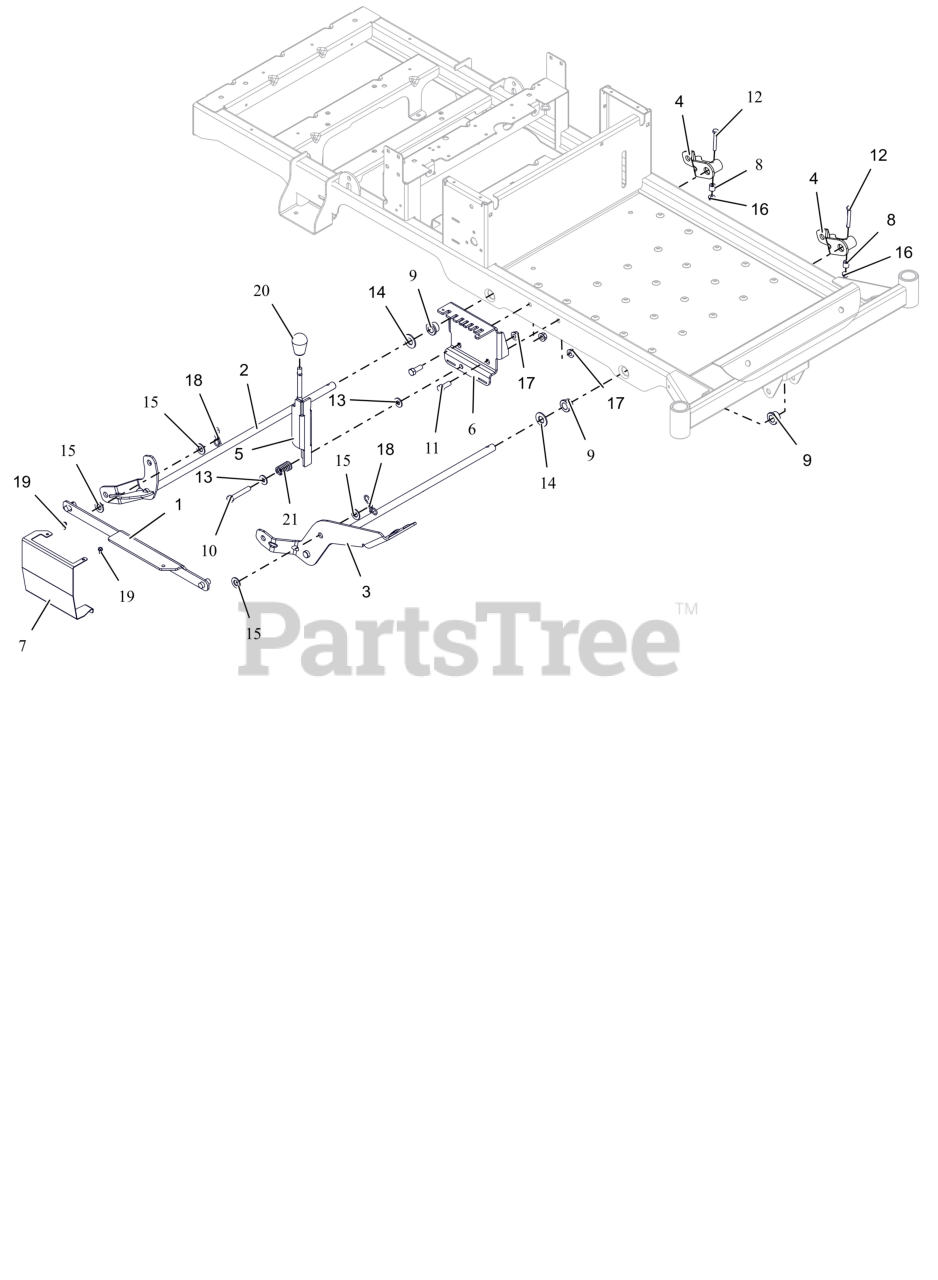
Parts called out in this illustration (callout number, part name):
1	WLDMT, LIFT /HOC LINK (RED)
2	WLDMT, REAR DECK LIFT (RED)
3	WLDMT, FOOTPEDAL (RED)
4	WLDMT, DECK LIFT ARM (RED)
5	WLDMT, HEIGHT OF CUT (RED)
6	PLATE, HEIGHT ADJUSTMENT (RED)
7	GUARD, DECK HOC (RED)
8	BSHG-SLV .265X.500X.500
9	BSHG-FLG .629X.879X.469X1.250
10	BLT,HEX .38-16X2.25 G5 ZCC
11	BLT,HEX .38-16X1.00 G5 ZCC
12	BLT, HEX .25-20X2.00 G5 ZCC
13	WSHR,FLT .375X.875X.083 ZCC
14	WSHR, FLT .656X1.313X.095 ZCC
15	WSHR-FL-NYL .518X1.000X.080
16	NUT-LK-CTR-FLG .25-20 ZC120
17	NUT-LK-CTR-FLG .375-16 GF ZCC
18	PIN, BOWTIE .091X1.875 ZCC
19	SCR,TAP #10-24X.50 HWH TR ZCC
20	KNOB,SOFT TEARDROP,PUSH-ON BLK
21	SPRG, COMPRESSION
